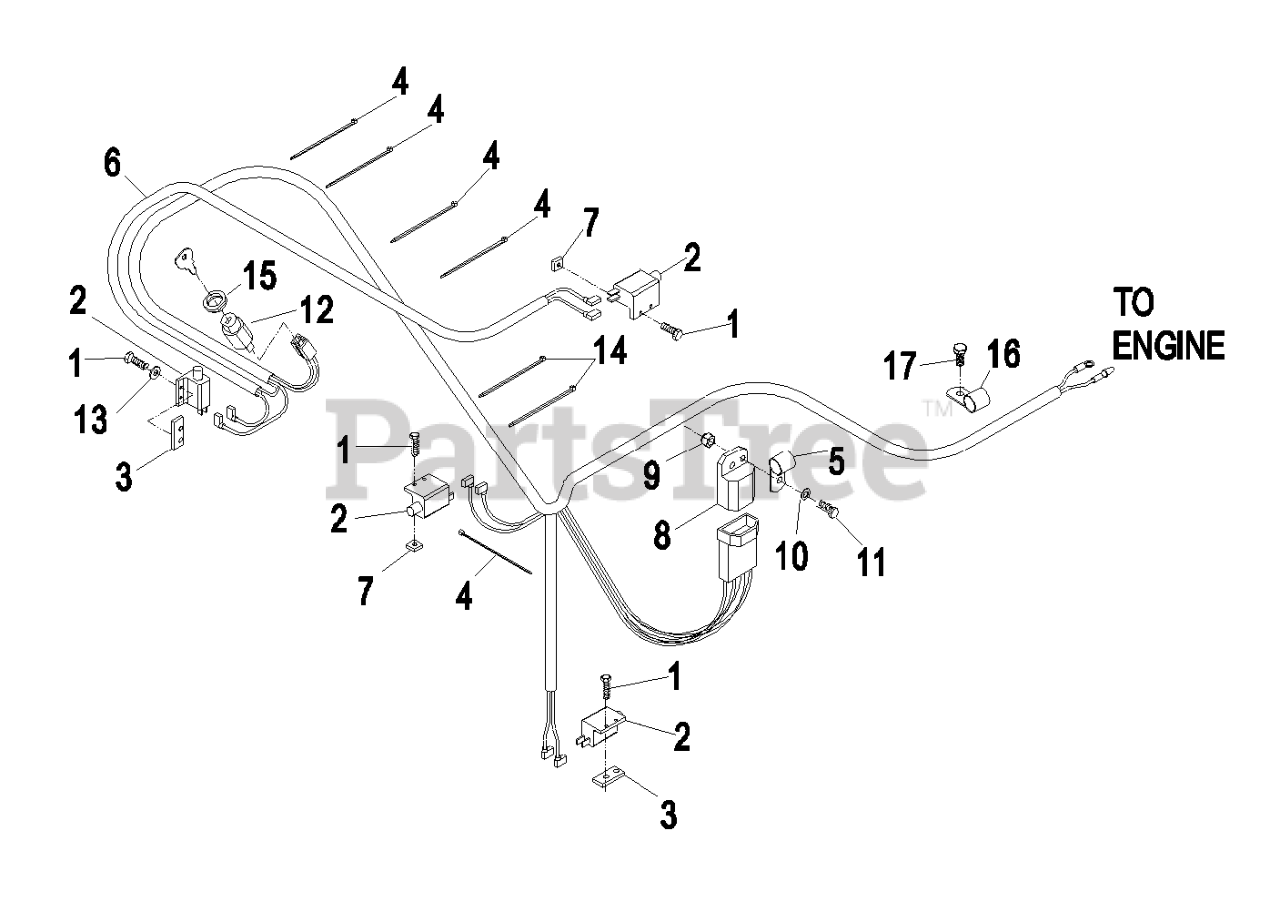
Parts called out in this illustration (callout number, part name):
1	SCREW-PPH
2	SWITCH-OPEN, NORMALLY
3	PLATE-TAPPED
4	TIE-CABLE
5	CLIP-LOOM
6	HARNESS,WIRING KA PULL ST
7	NUT-SQH
8	MODULE-INTERLOCK
9	NUT-LOCK, NI
10	WASHER-FLAT
11	SCREW-HH
12	SWITCH & KEY (INCLUDES NU
13	WASHER-FLAT
14	TIE-PLASTIC
15	NUT-SWITCH, IGNITION
16	CLIP-LOOM
17	SCREW-HH
